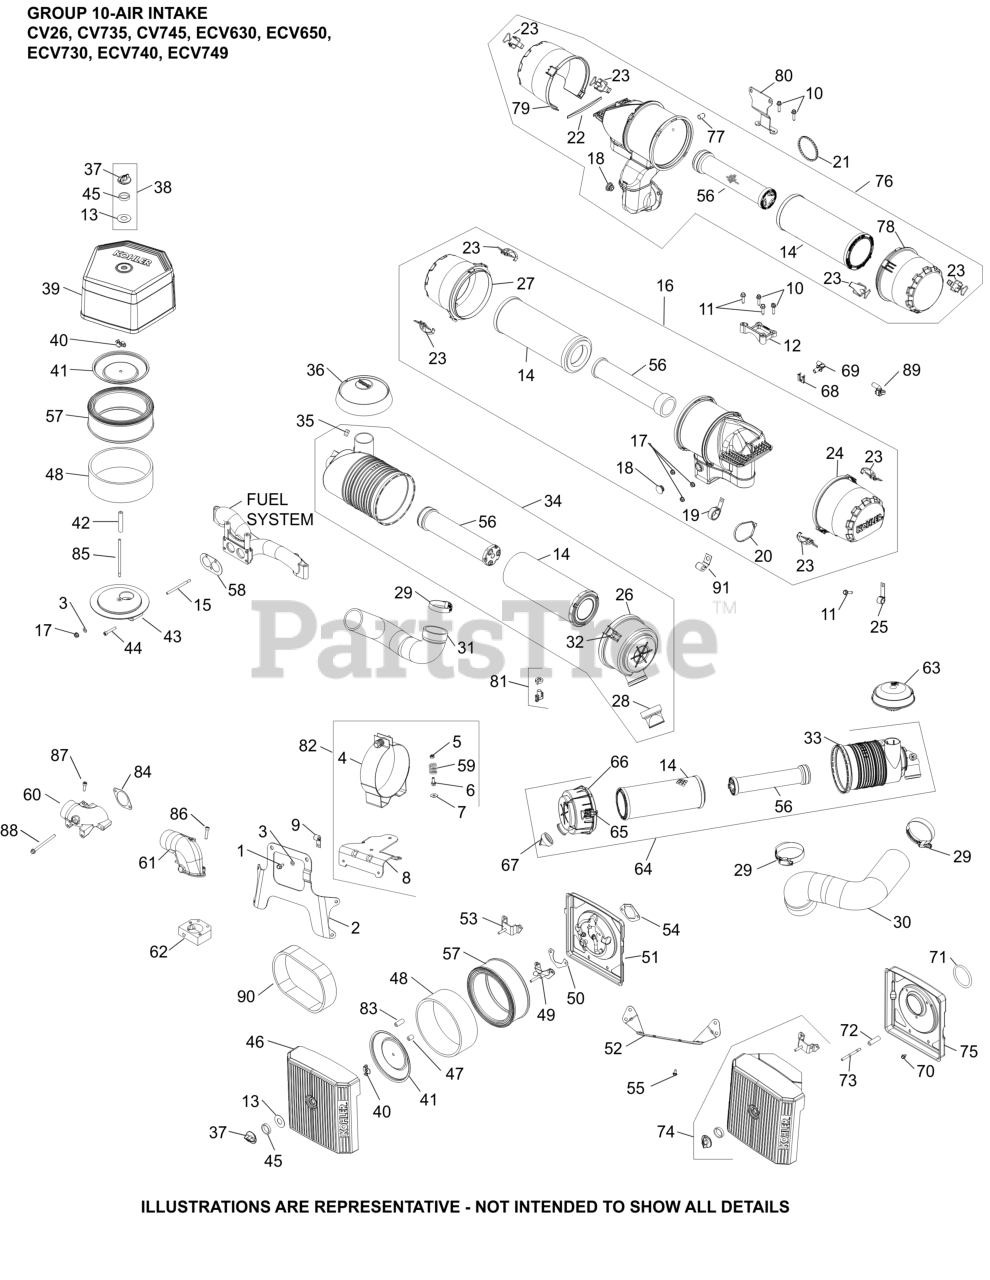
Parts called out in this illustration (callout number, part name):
1	SCREW, THREAD FORMING
2	BRACKET, MAIN SUPPORT
4	BRACKET, AIR CLEANER
5	NUT, LOCK M6X1.0
6	SCREW, FLG M6X1.0X16
7	WASHER, FLAT 1/4"
8	BRACKET, AIR CLEANER MOUNTING
14	ELEMENT, AIR FILTER - PRIMARY
17	NUT, FLG M6X1.0
25	CLIP, CABLE
26	COVER ASSEMBLY
28	VALVE, VACUATOR
29	CLAMP, HOSE-USE 25 237 21-S
29	CLAMP, HOSE
31	HOSE, AIR CLEANER
32	LATCH ASSEMBLY
34	AIR CLEANER ASSY
35	PLUG, PIPE
36	HOOD, INLET
56	ELEMENT, AIR FILTER - SAFETY
59	SPRING, AIR CLEANER BRACKET
